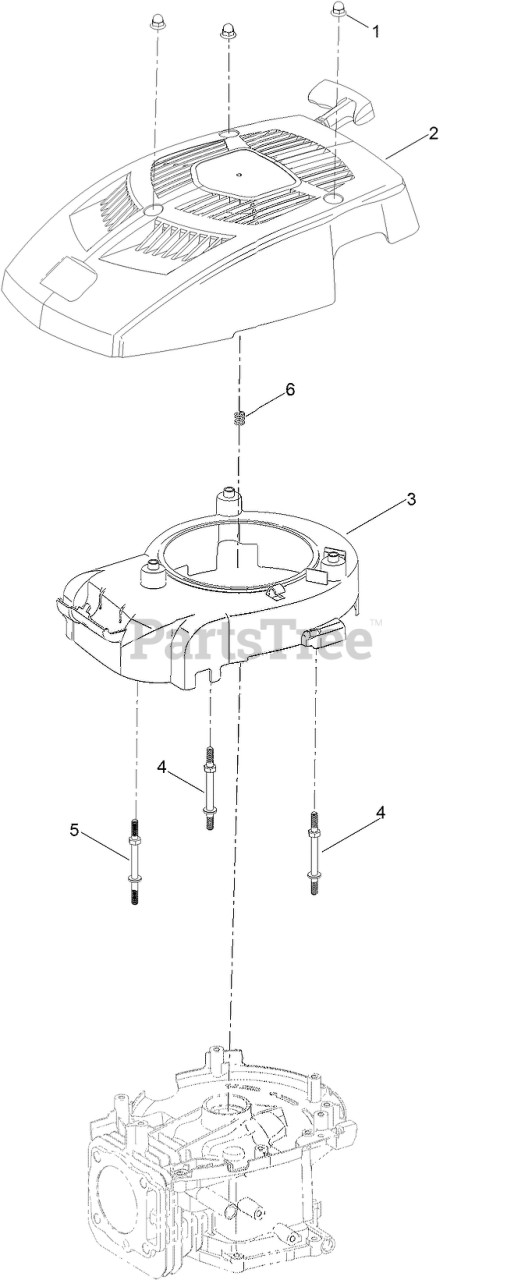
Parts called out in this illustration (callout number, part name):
1	NUT-ACORN
2	RECOIL SHROUD ASM
3	SHROUD-FAN
4	STUD-SHROUD
5	STUD-SHROUD
6	SPRING-COMPRESSION, RECOIL
